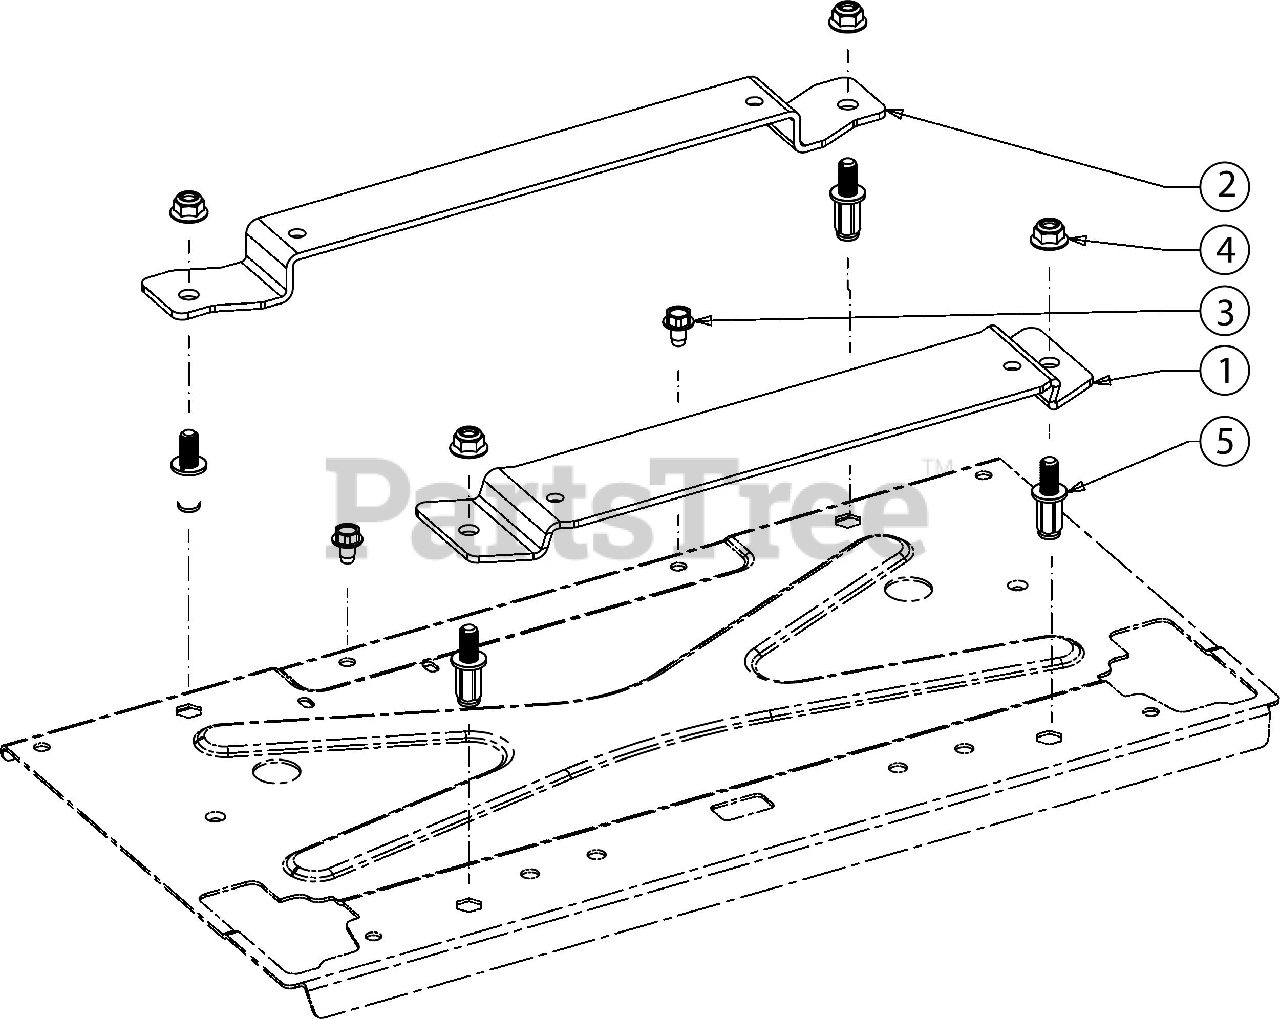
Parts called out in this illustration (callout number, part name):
1	FRONT SEAT BRACKET
2	REAR SEAT BRACKET
3	SCREW 5/16-18 x .500
5	HEX RIVET 3/8-16 X .750
